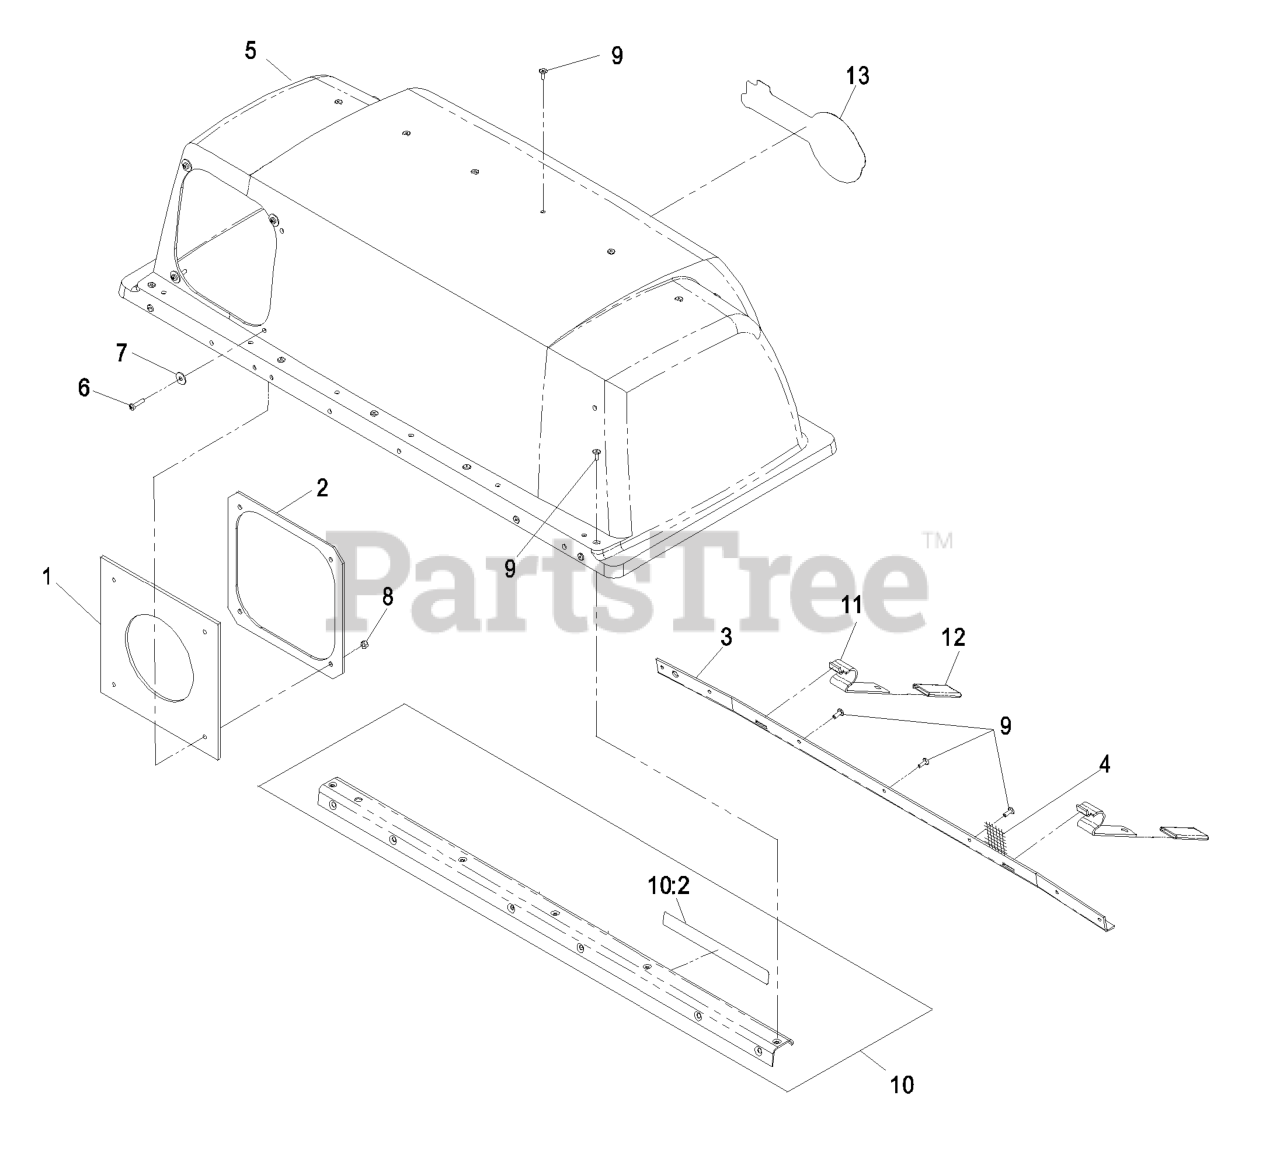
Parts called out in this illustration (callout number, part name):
1	SEAL-CHUTE
2	CLAMP-SEAL
3	SUPPORT-SCREEN
4	SCREEN-BAGGER
5	TOP-BAGGER
6	SCREW-PPH
7	WASHER-FLAT
8	NUT-LOCK, NI
9	RIVET-BLIND
10	STIFFENER AND DECAL
10:2	DECAL-CAUTION, BAGGER
11	LATCH-BAGGER, TOP
13	DECAL, EXMARK LOGO
